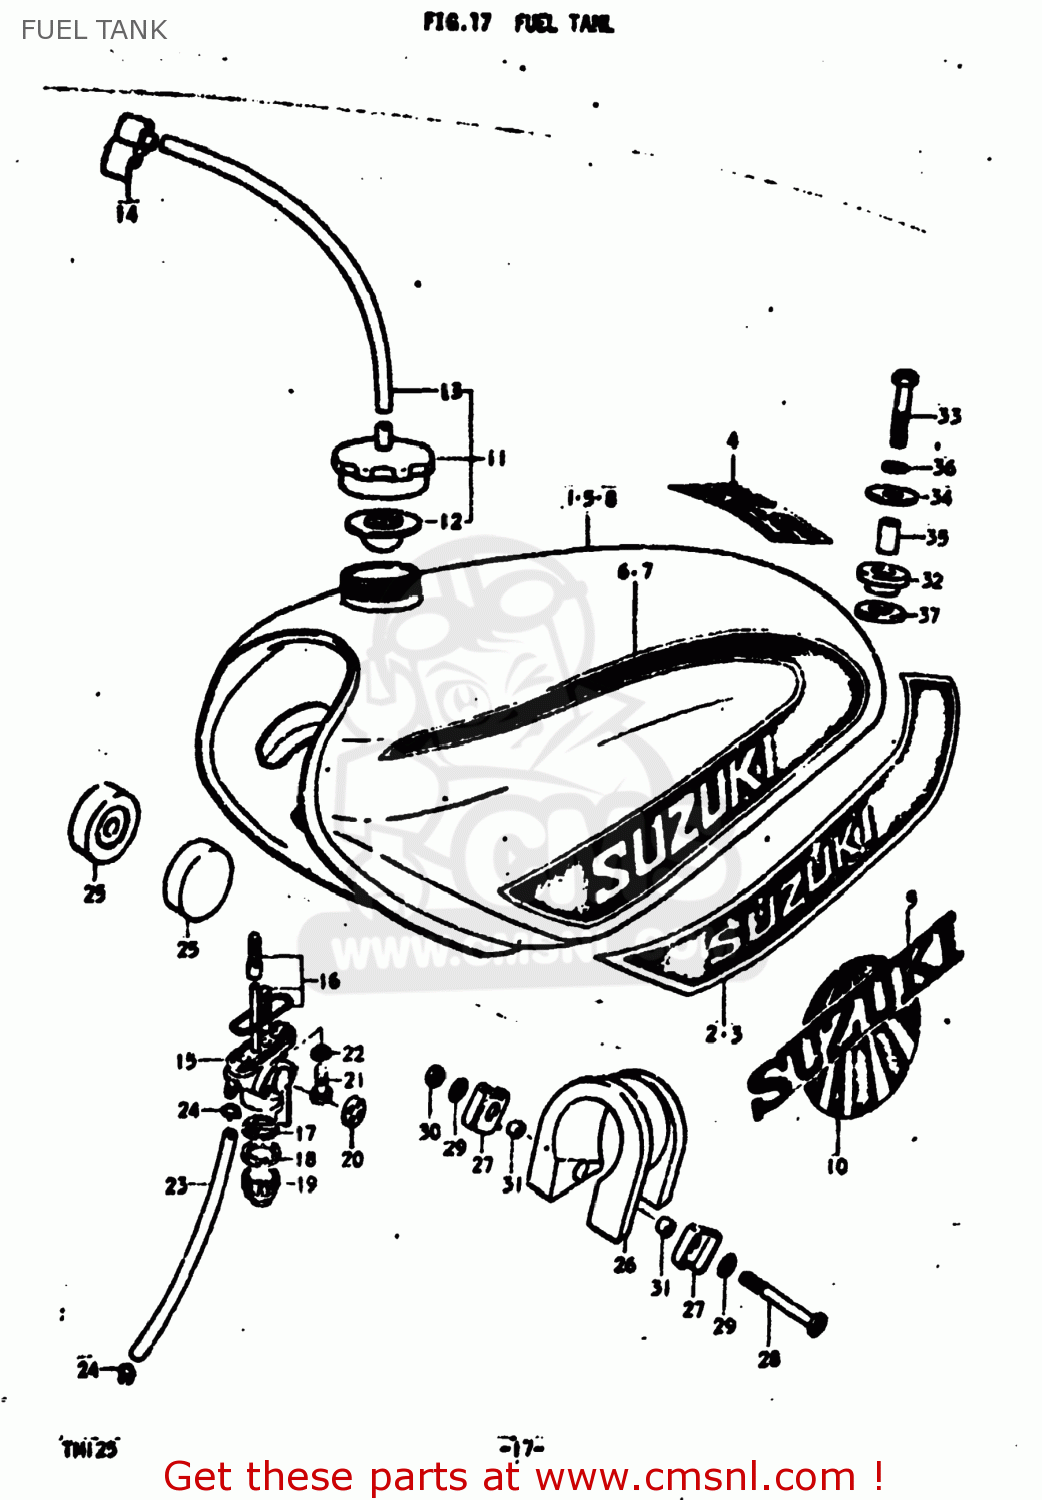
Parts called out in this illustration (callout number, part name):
1	TANK ASSEMBLY,FUEL
5	TANK ASSEMBLY,FUEL
6	TAPE,FUEL TANK
7	TAPE,FUEL TANK
8	TANK ASSEMBLY,FUEL
9	EMBLEM
10	TAPE,FUEL TANK
11	CAP ASSY,FUEL TANK FILLER
12	GASKET,FUEL TANK CAP (NAS)
13	HOSE
14	CLAMP,FUEL
15	COCK ASSEMBLY,FUEL
16	COCK ASSEMBLY,FUEL
17	NET,STRAINER
18	GASKET,FILTER (NAS)
19	CUP,FUEL COCK STRAINER
20	GASKET,LEVER (NAS)
21	SCREW
22	GASKET
23	HOSE
24	CLIP
25	CUSHION
26	CUSHION,FUEL TANK,REAR
27	CLIP
28	BOLT
29	WASHER 6MM
30	NUT
31	SPACER (6.1X8X5.2)
32	CUSHION
33	** SUPERSEEDED
34	WASHER
35	SPACER
36	LOCK WASHER
37	CUSHION
